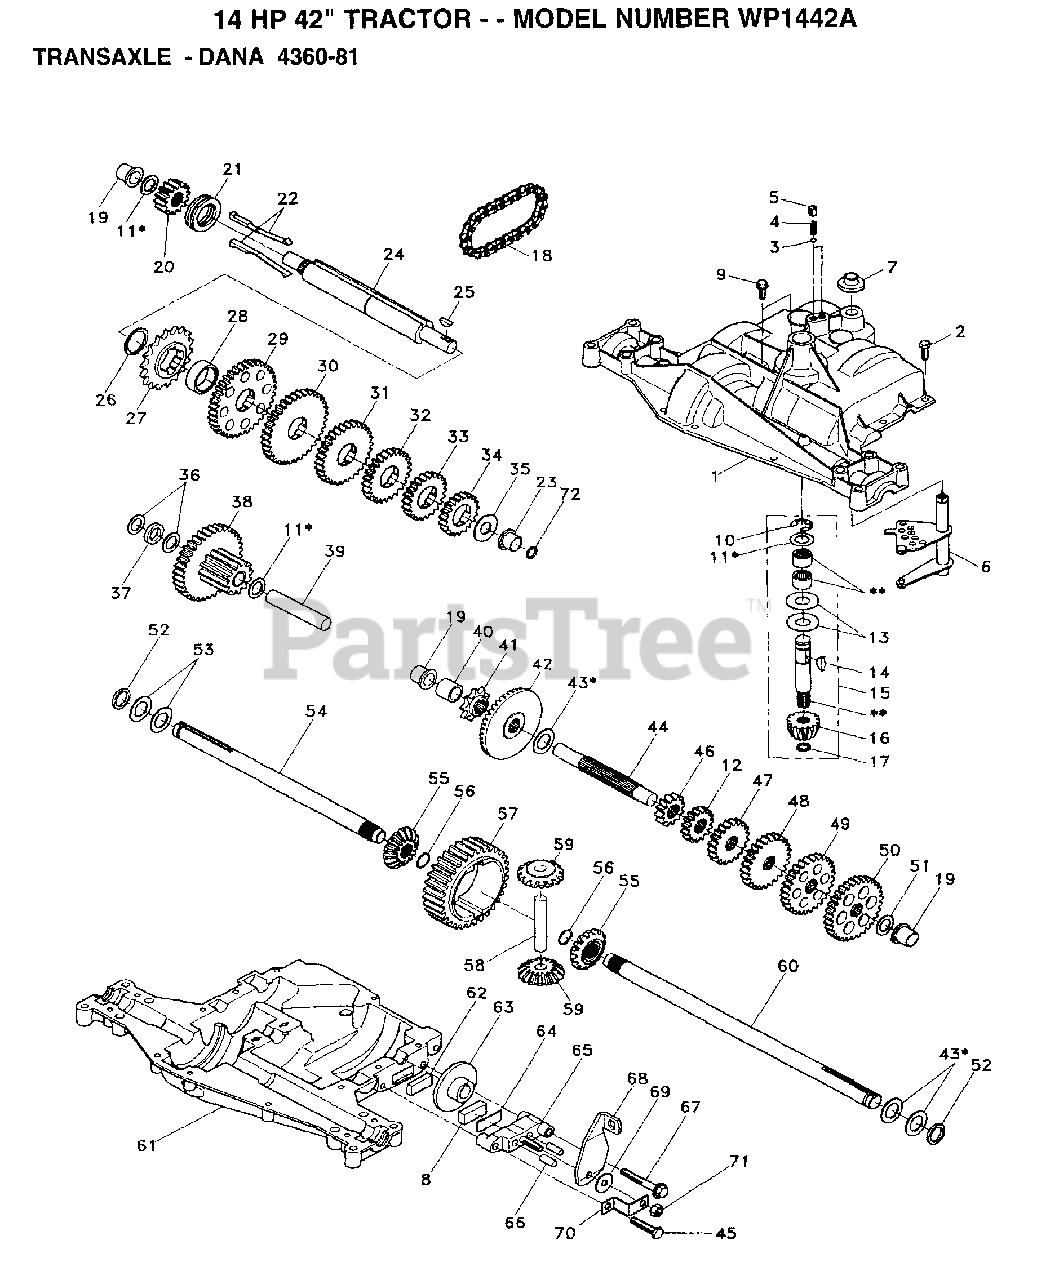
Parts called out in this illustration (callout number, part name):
1	HOUSING, UPPER
3	BALL, DETENT
4	SPRING, DETENT
5	SCREW, SET
6	KIT, SHIFTER ASSEMBLY
7	BOOT, SHIFTER
8	PUCK, FRICTION
9	SCREW TAPPING WITH SEALER
10	RING, RETAINING
11	ASSY, KIT, SHIM .625 SHAFT
12	GEAR, SPUR, 15T
13	WASHER, PLAIN .632 X 1.38 X .046
14	KEY, WOODRUFF, #9
15	ASSY KIT INPUT SHAFT
16	PINION BEVEL 14 TEETH
17	RING, RETAINING
18	CHAIN, 24 PITCHES
19	BEARING, FLANGE
20	GEAR, SPUR, 14 TEETH
21	COLLAR, CLUTCH
22	ASSY, KIT, CLUTCH KEYS
23	BEARING, FLANGE
24	SHAFT, INTERMEDIATE
25	KEY, WOODRUFF, #61
26	RING, RETAINING
27	SPROCKET, 18 TEETH
29	GEAR, SPUR, 37 TEETH
30	GEAR, SPUR, 35T
31	GEAR, SPUR, 30 TEETH
32	GEAR, SPUR, 25 TEETH
33	GEAR, SPUR, 22 TEETH
34	GEAR, SPUR, 19 TEETH
35	WASHER, PLAIN .640 X 1.37 X .061
36	WASHER, PLAIN .632 X 1.00 X .026
37	SPACER .630 X 1.00 X .169
38	ASSY GEAR COMB 12&35 TEETH
39	SHAFT, IDLER
40	SPACER .635 X .875 X .755
41	SPROCKET, 9 TEETH
42	GEAR, BEVEL, 42 TEETH
43	ASSY, KIT, SHIM .750 SHAFT
44	SHAFT, DRIVE
45	SCREW TAPPING
46	GEAR SPUR, 12 TEETH
47	GEAR, SPUR, 20 TEETH
48	GEAR, SPUR, 25 TEETH
49	GEAR, SPUR, 28 TEETH
50	GEAR, SPUR, 31 TEETH
51	WASHER, PLAIN .632 X 1.00 X .060
52	WASHER, NEOPRENE
53	WASHER, PLAIN .758 X 1.25 X .031
54	AXLE LEFT HAND
55	GEAR MITER 15 TEETH
56	RING, RETAINING
57	GEAR, SPUR, 32 TEETH
58	SHAFT, CROSS
59	GEAR, MITER, 15 TEETH
60	AXLE, R.H.
61	HOUSING, LOWER
62	PUCK, FRICTION
63	DISC, BRAKE
65	JAW, BRAKE
66	PIN, DOWEL
67	SCREW, SELF-TAPPING
68	LEVER ACTUATING
69	WASHER, PLAIN .321 X 1.00 X .055
70	BRACKET, ANTI-ROTATION
71	LOCKNUT 5/16-24
